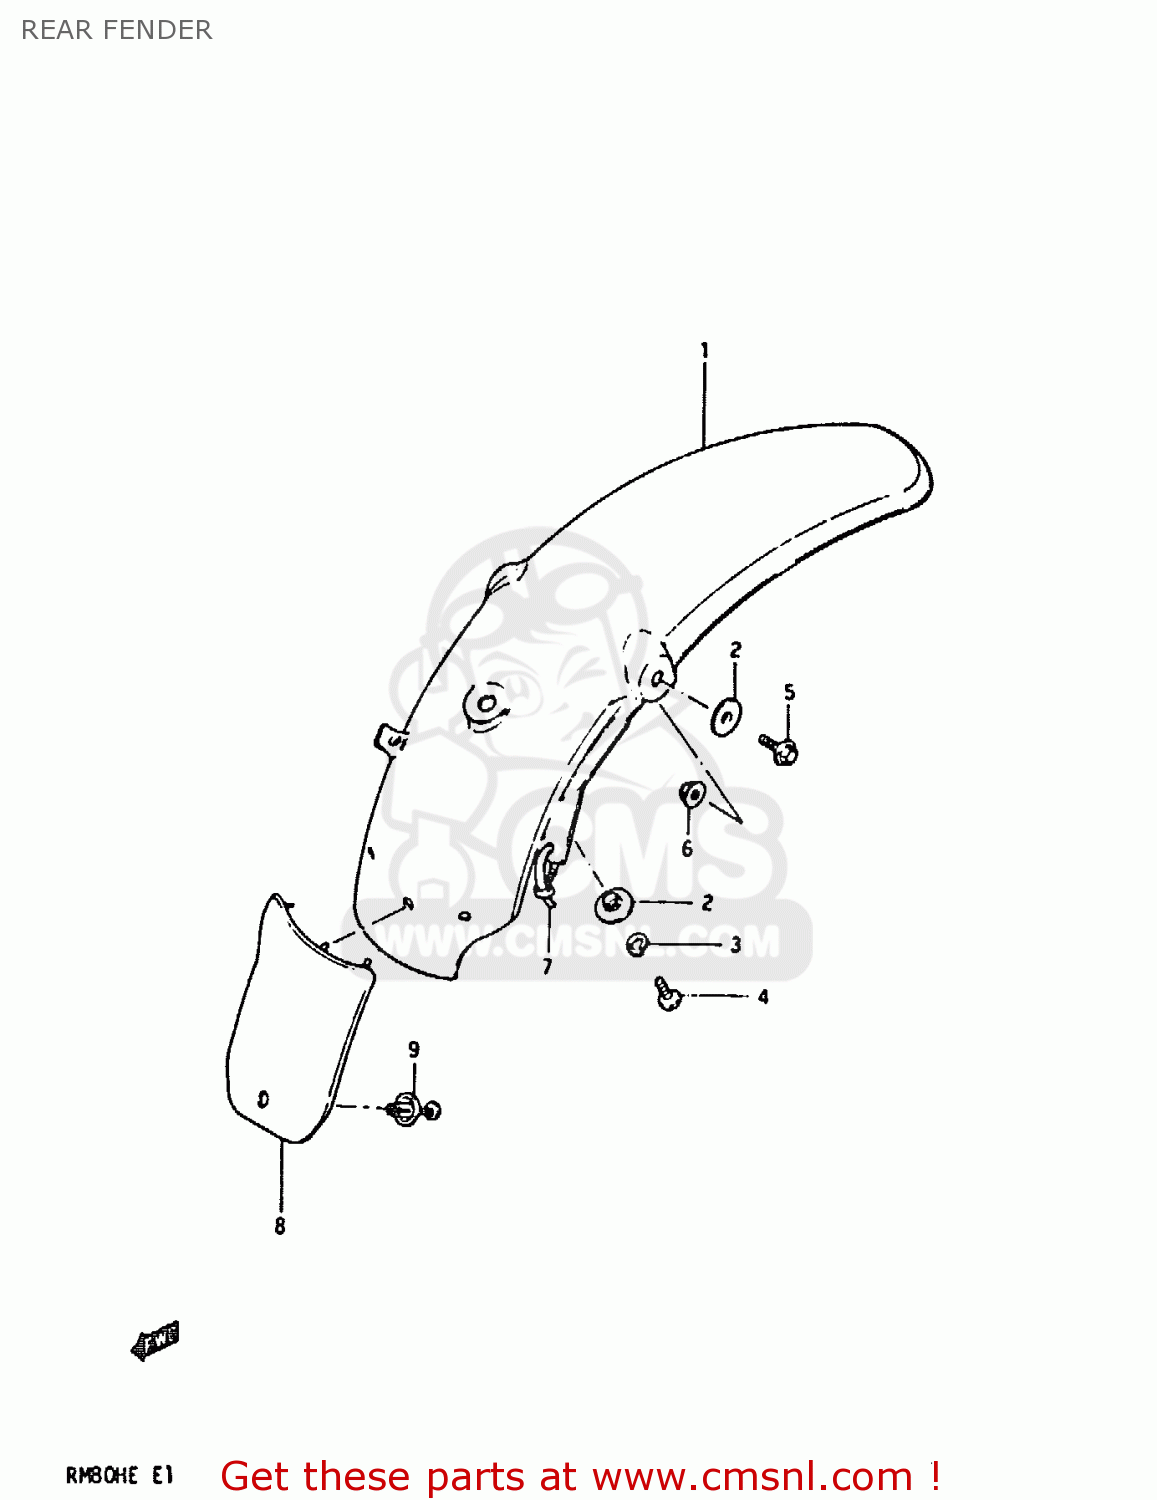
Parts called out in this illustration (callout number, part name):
1	FENDER, REAR (YELLOW)
2	WASHER
3	LOCK WASHER
4	BOLT, UPPER
5	BOLT,REAR
6	NUT
7	CLAMP
8	GUARD,MUD
9	CLIP
